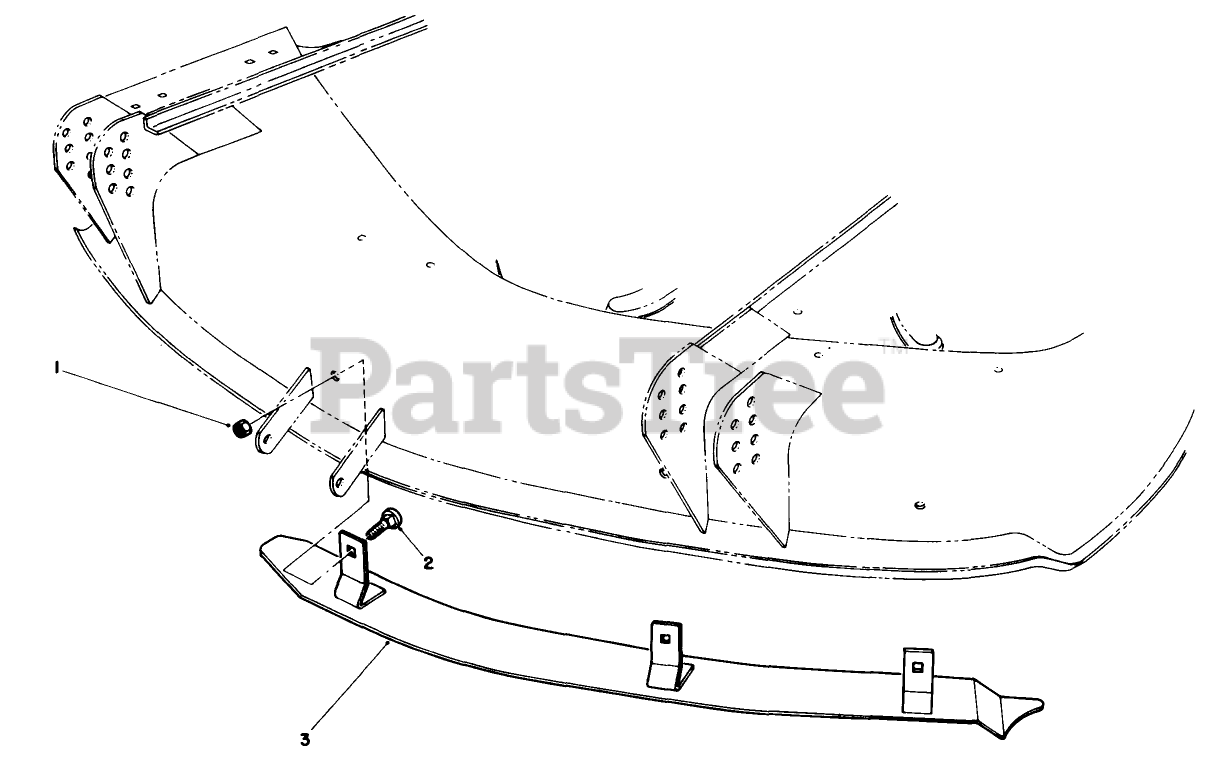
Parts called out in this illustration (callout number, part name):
1	NUT-LOCK, NI
2	SCREW-CARR
3	Baffle Assembly
